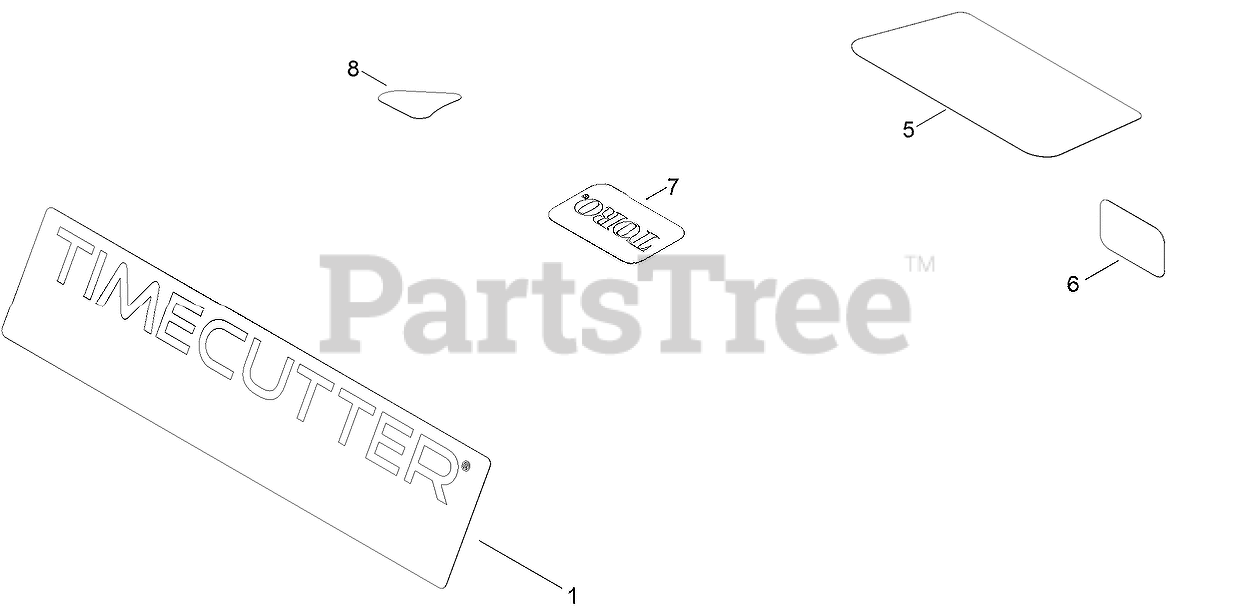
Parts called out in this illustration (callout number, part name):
1	DECAL-TIMECUTTER
5	DECAL-ENGINE
6	PLACARD-INTAKE
8	DECAL-DRAIN, OIL
